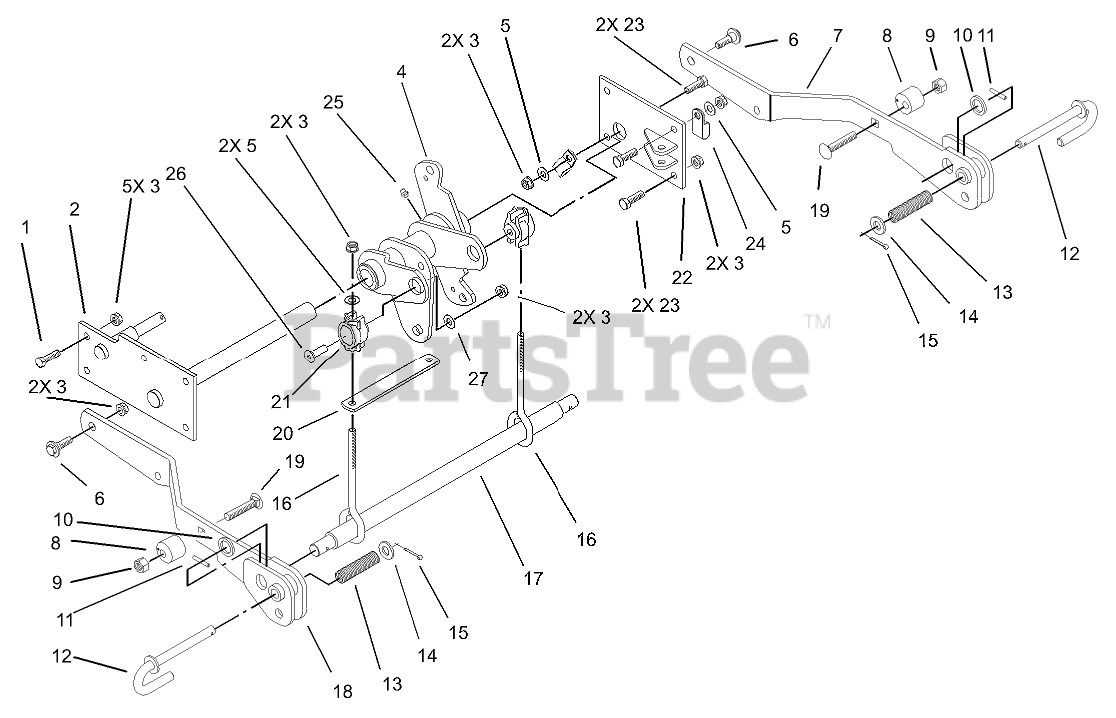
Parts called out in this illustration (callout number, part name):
1	SCREW-HH
2	SUPPORT-LIFT, DECK
3	NUT-LOCK, NI
4	BELLCRANK AND BUSHING ASM
5	WASHER-FLAT
6	BOLT-SHOULDER
7	ARM-LIFT, LH
8	STOP-LIFT, ADJ.
9	NUT-LOCK, NI
10	WASHER-FLAT
11	PIN-ROLL
12	PIN - J
13	SPRING-COMPRESSION
14	WASHER-FLAT
15	PIN-COTTER
16	ROD-LIFT
17	BAR-LIFT
18	Arm-Lift, RH
19	SCREW-CARR
20	SPACER-STRAP
21	SLEEVE-LIFT
22	PLATE - LH SUPPORT
23	SCREW-HH
24	CLAMP-TUBE
25	FITTING-GREASE
26	SCREW-HSFH
27	WASHER-FLAT
